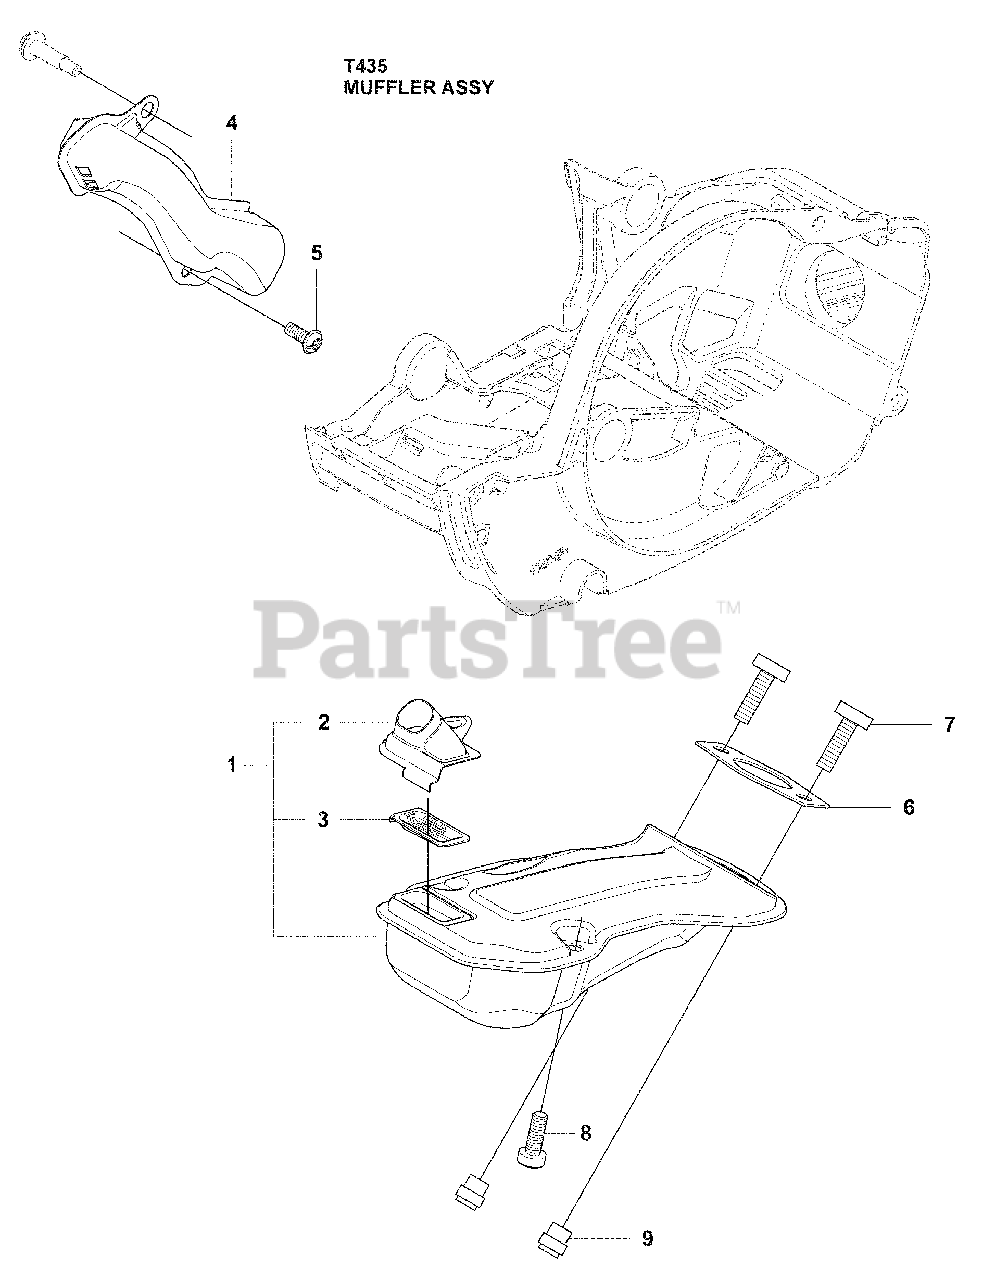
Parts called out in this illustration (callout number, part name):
1	Muffler
2	Muffler guide
4	Exhaust pipe
5	Screw
